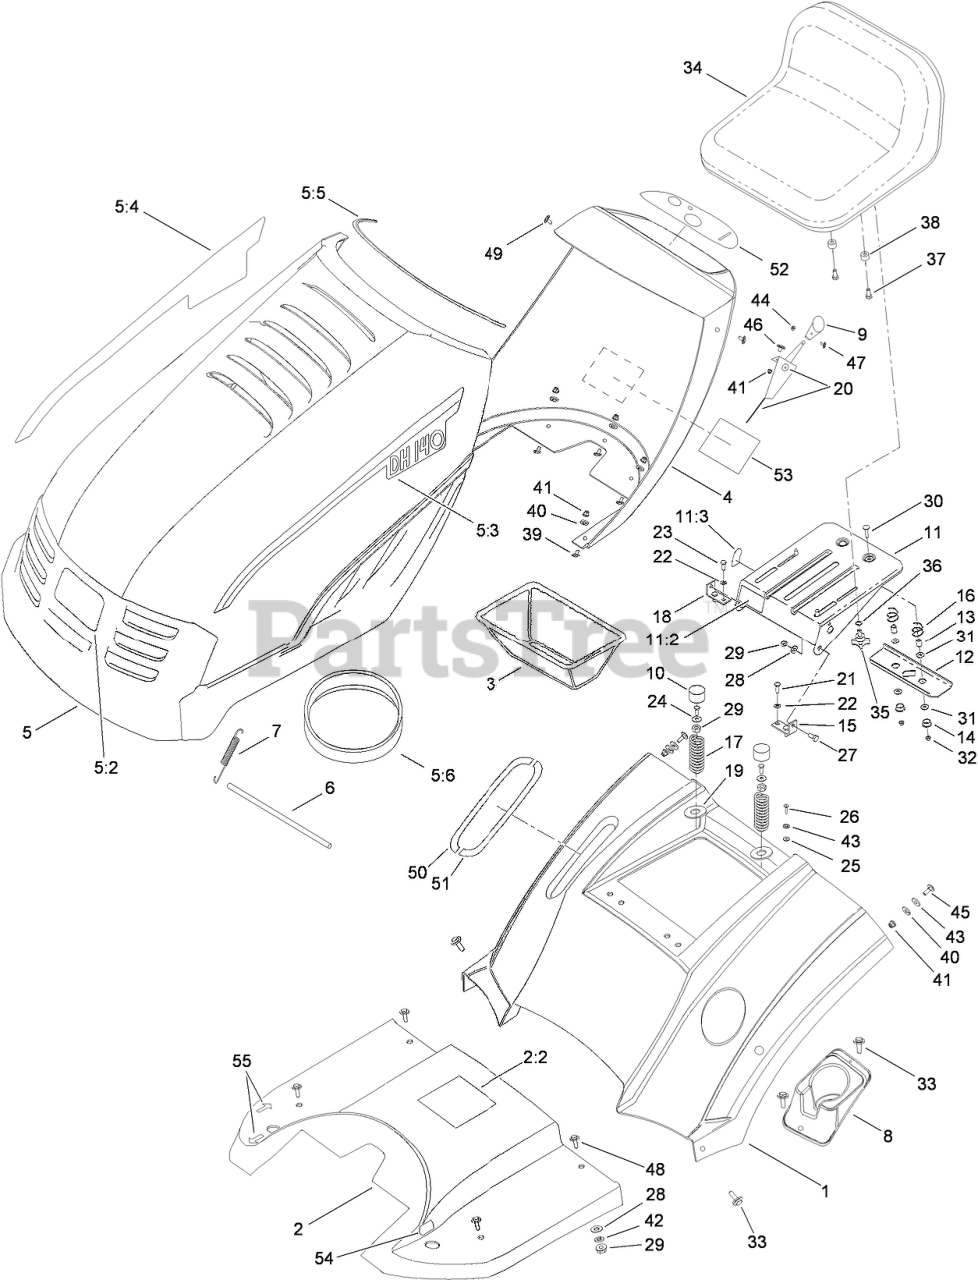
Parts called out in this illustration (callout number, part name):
1	FENDER-REAR
2	FOOT REST ASSEMBLY
2:2	DECAL-DANGER
3	BOX-BATTERY
4	PANEL-DASH
5	HOOD ASM
5:3	DECAL-DH 140 (LH)
5:4	DECAL-DH 140 (RH)
5:5	RUBBER-PURL
5:6	GASKET-FOAM
6	BAR-SAFETY
7	SPRING-HOOD
8	BOX-DRINK
9	KNOB-THROTTLE/CHOKE
10	CAP-HUB
11	BRACKET-SUPPORT, SEAT
11:2	DECAL-DANGER
11:3	DECAL-SWITCH
12	BRACKET
13	SPACER-SPLIT
14	BUSHING
15	HOLDER-SUPPORT, LEFT
16	SEAT-SPRING
17	SPRING-SEAT
18	HOLDER-SUPPORT, RIGHT
19	WASHER-SEAT SPRING
20	CABLE-THROTTLE/CHOKE
21	SCREW-HH
22	WASHER-SPRING
23	SCREW-HH
24	WASHER-PLAIN
25	WASHER-FINISH
27	SCREW-SUPPORT, SEAT
28	WASHER-PLAIN
29	NUT-LOCK, NI
30	SCREW-CARR
31	WASHER-FLAT
32	NUT-LOCK
35	KNOB-ADJUST
36	WASHER-SPRING
37	SCREW-HHF
38	SPACER
39	SCREW-HEX
40	WASHER-FLAT
41	NUT-LOCK
42	WASHER-RUBBER
43	WASHER-RUBBER
44	NUT-HEX
46	SCREW-FLAT HEAD
50	DECAL-MOWING LIFT, RIGHT
51	DECAL-MOWING LIFT, LEFT
52	DECAL-PANEL
53	DECAL-INSTRUCTIONS, OPERATING
54	DECAL-BRAKE, PARKING
55	DECAL-TRAVEL
